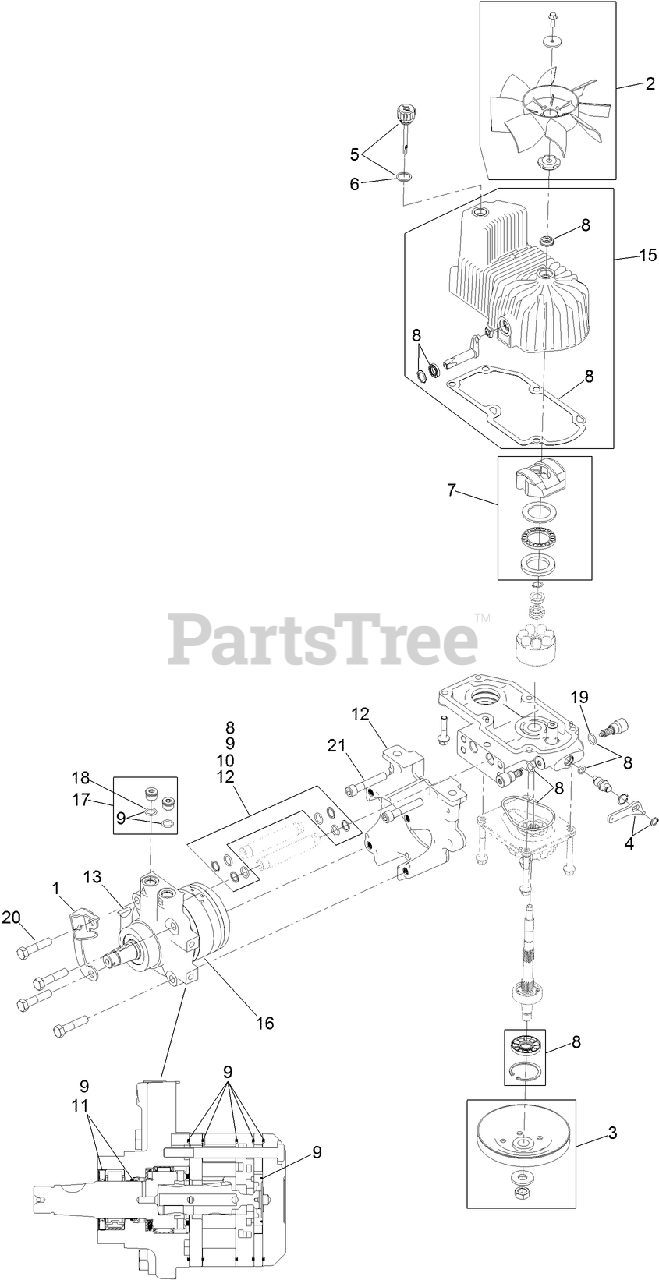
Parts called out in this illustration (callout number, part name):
1	BRACKET-ANCHOR, CABLE
2	FAN KIT
3	PULLEY KIT
4	HANDLE-BYPASS VALVE, HYDRO
5	DIPSTICK-HYDRO W/GASKET
6	GASKET-DIPSTICK, HYDRO
7	SWASH BLOCK KIT
8	PUMP SEAL KIT
9	MOTOR SEAL KIT
10	TUBE SEAL KIT
11	OUTPUT SHAFT SEAL KIT
12	NOSE CUP-UHT
13	KEY-WOODRUFF
15	Housing-RH
16	MOTOR-HYDRAULIC RH 240CC
17	MAGNETIC PLUGS SERVICE KIT
18	O-RING
19	O-RING-CHECK VALVE
20	SCREW HH
21	SCREW-HSH
